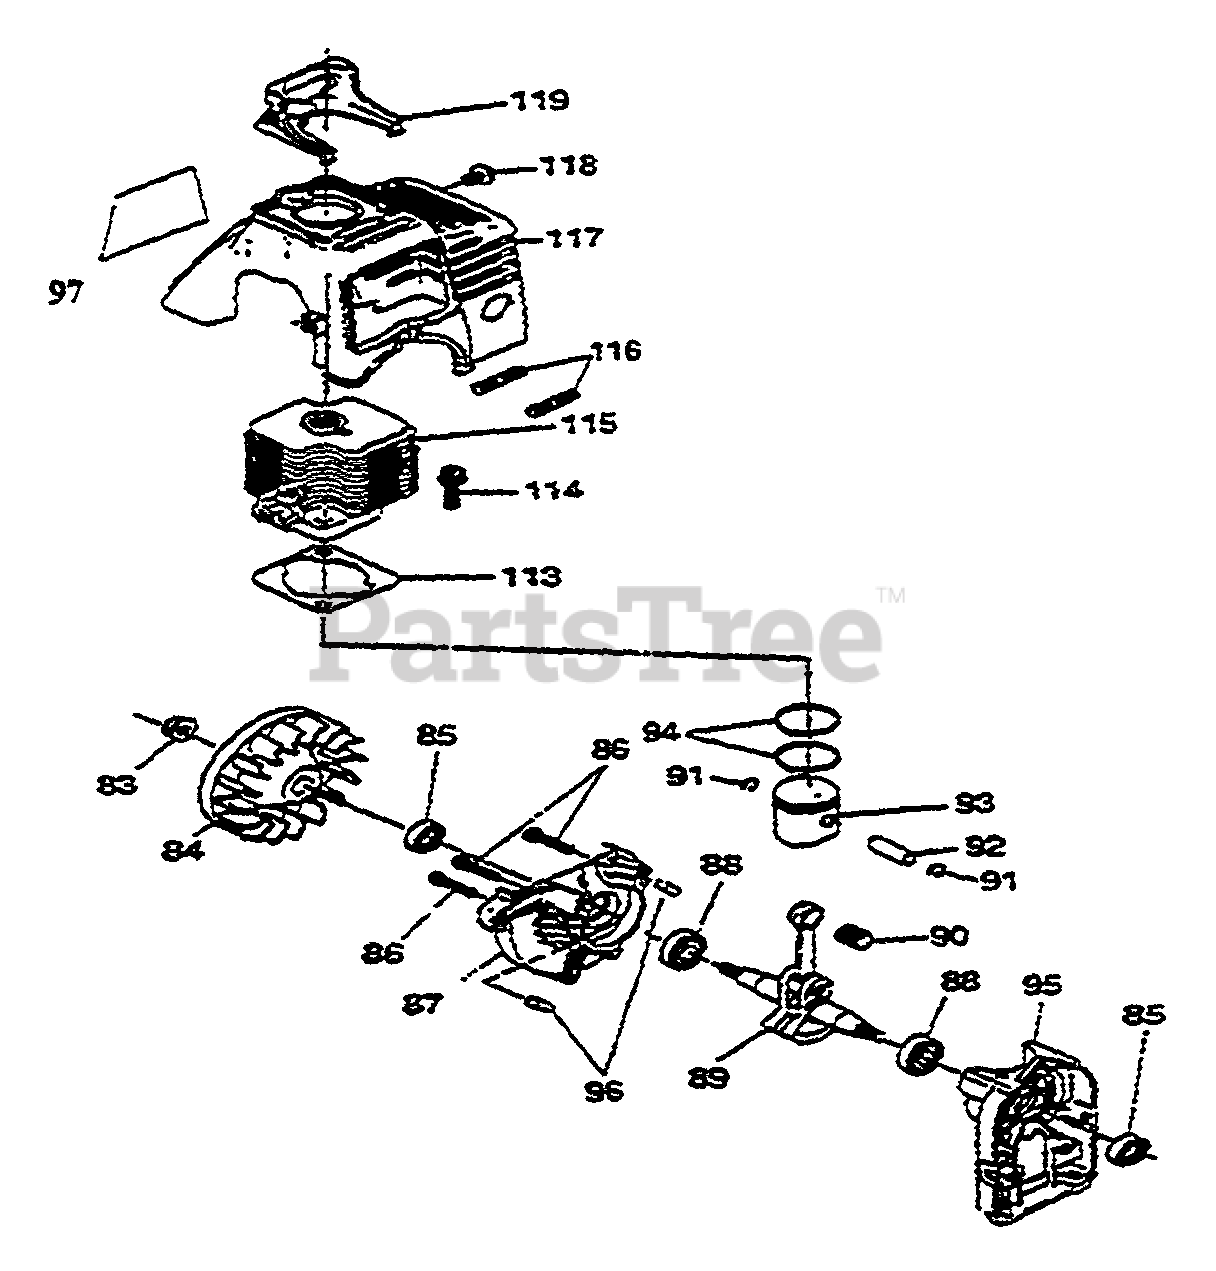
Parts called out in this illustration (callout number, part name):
83	NUT, CONICAL SPG.
85	OIL SEAL
87	CASE, DRIVE
88	BEARING, BALL
89	CRANKSHAFT ASSY
90	BEARING, NEEDLE
91	CLIP, PISTON PIN
92	PIN, PISTON
94	RING, TOP
95	CASE, STARTER
96	DOWEL PIN
113	GASKET, CYLINDER
114	BOLT, FLANGE
116	BOLT, STUD
117	COVER, TOP
118	SCREW & WASHER
119	GUARD, SPARK PLUG
